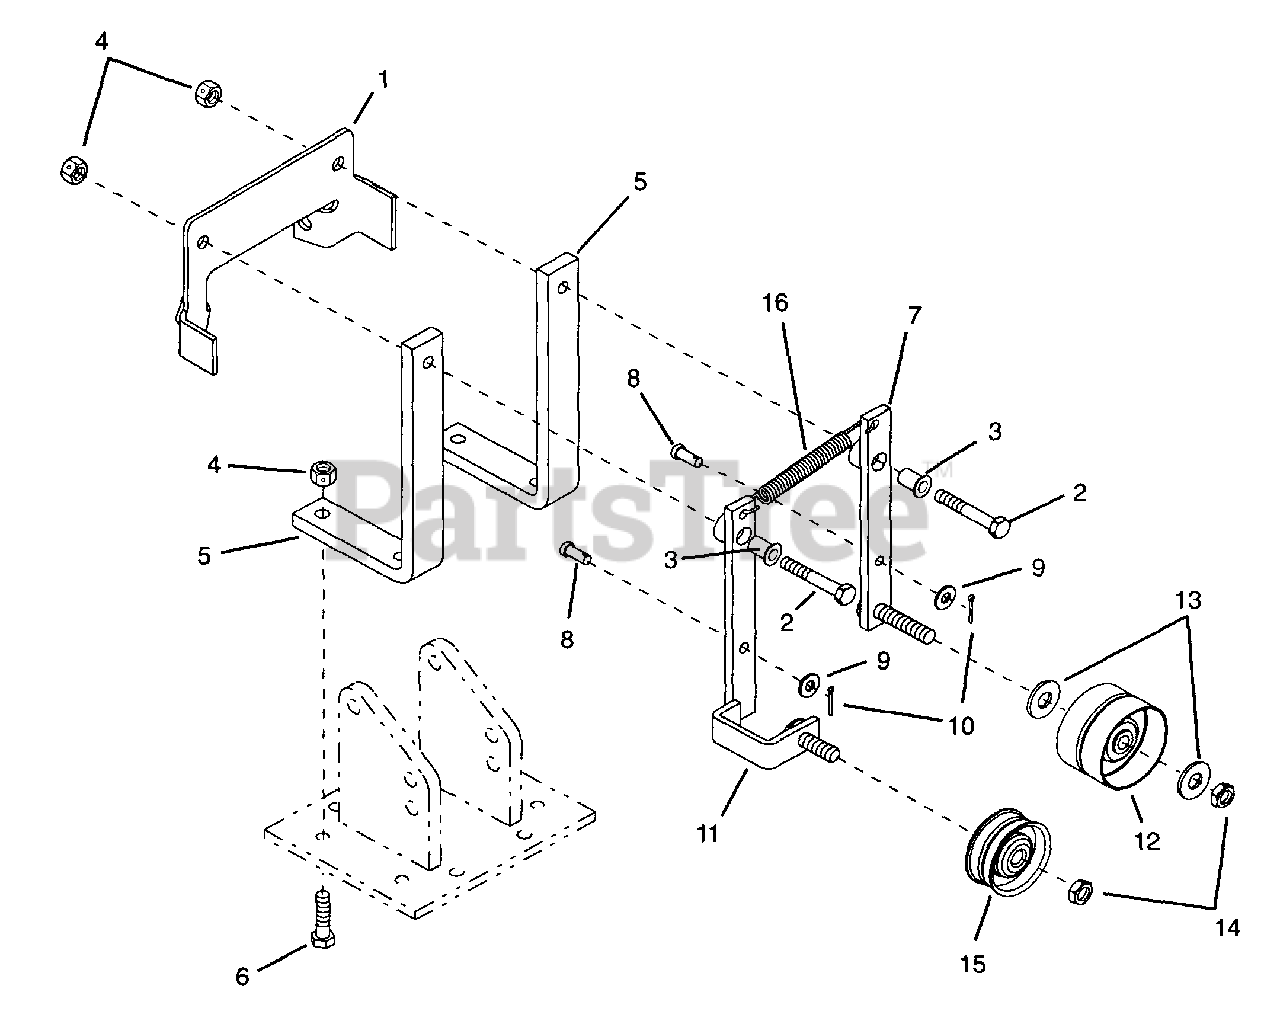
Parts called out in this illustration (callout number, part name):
1	PLATE, ANCHOR
2	@BLT-HEX .31-18X2.00 GR5 YWZC
3	BSHG-FLG .325X.465X.831X.685
4	@NUT-LK-CTR .31-18 YWZC
5	SHIFT MOUNTING BAR
6	@BLT-HEX .31-18X1.25 GR5 YWZC
7	IDLER ARM - FORWARD
8	PIN-CLEV .25X.62
9	@WSHR-FL-STL.281X.62X.065 YWZC
10	PIN-COTR .062 X .50
11	IDLER ARM - REVERSE
12	IDLER-FLAT 2.25 X .38
13	@WSHR-FL-STL.438X1.00X.083 YWZ
14	@NUT-LK-CTR-JAM .375-16 YWZC
15	IDLER-FLAT 2.000X.375
16	SG-TENS .047X.44X3.5 WLD 3
